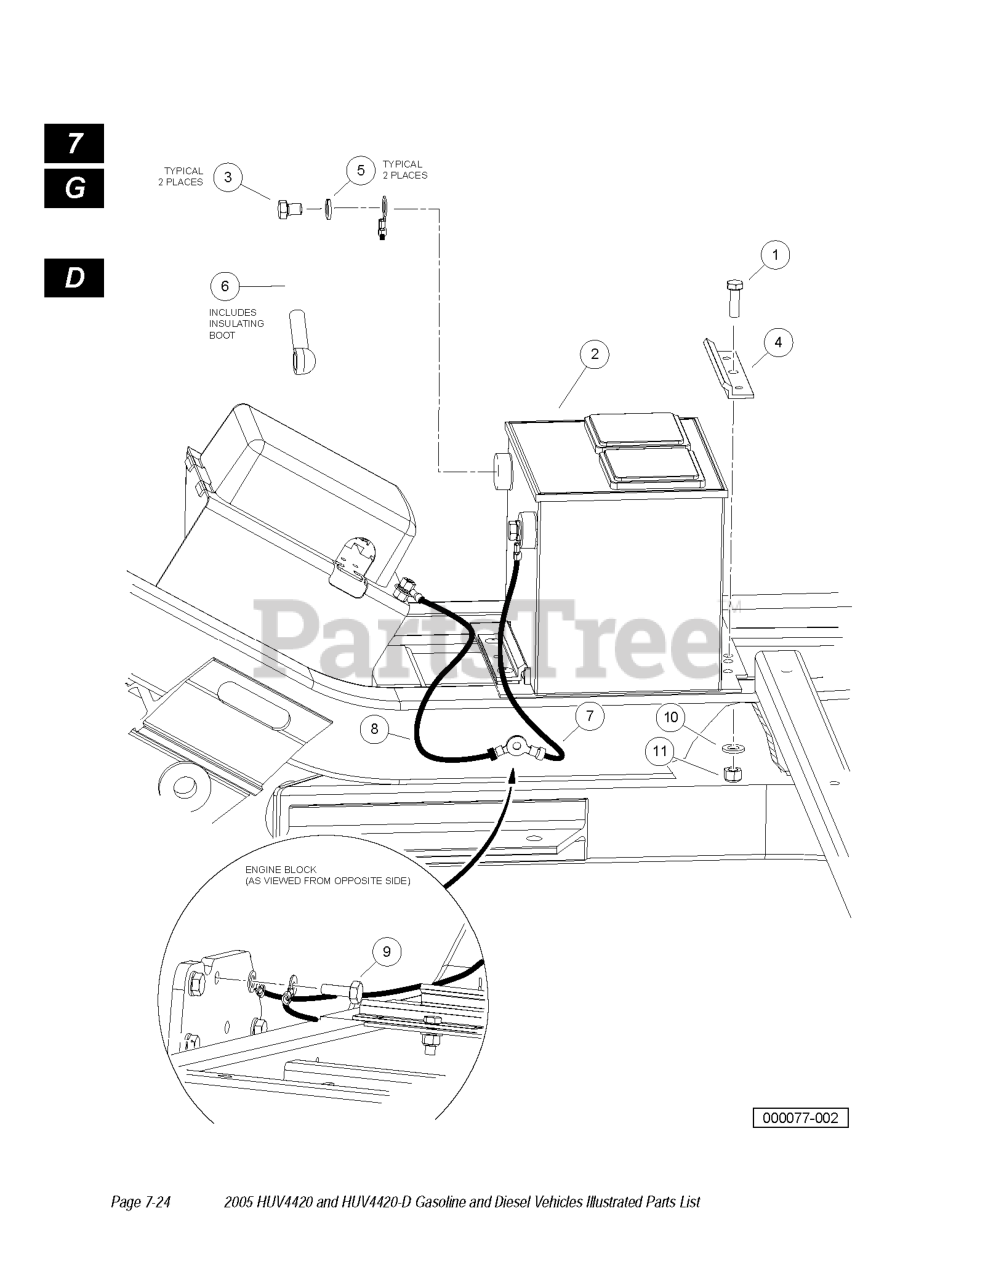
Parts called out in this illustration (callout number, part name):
1	SCREW HEX CAP
2	BATTERY, 12 VOLT
4	CLAMP - BATTERY
5	LOCKWASHER, 3/8 STAINLESS STL
6	WIRE ASM, #6 RED, AWD
7	WIRE ASM, #6 BLK, AWD, 350
8	WIRE ASM, #6 BLK, AWD, 325
9	BOLT, M10 X 1.25 X 25 LOCTITE
10	WASHER, 5/16 TYPE A FLAT
11	LOCKNUT, 5/16-18 NYLON INSERT
